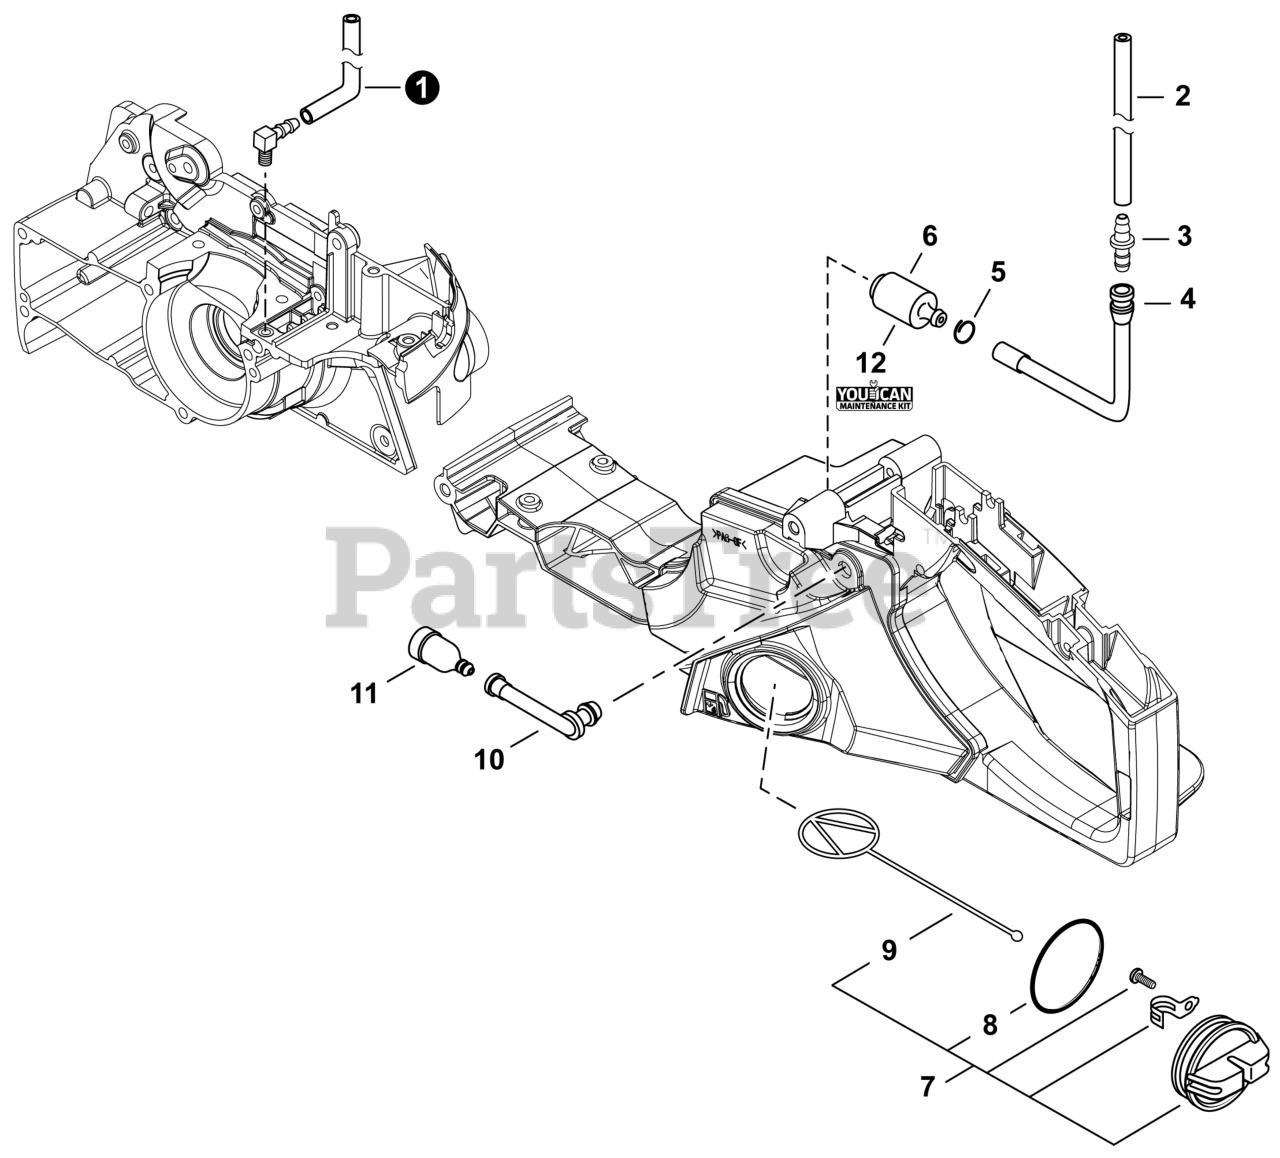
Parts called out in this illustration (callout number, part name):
1	PIPE, FUEL 3x6x100
2	PIPE, FUEL 3x6x75
3	CONNECTOR, PIPE
4	PIPE, FUEL
6	FILTER, FUEL
7	CAP ASSY, FUEL
8	O-RING 29
9	CONNECTOR, CAP L= 60 MM
10	PIPE, FUEL VENT 2x5x43
11	VENT ASSY
12	TUNE-UP KIT - YOUCANT
